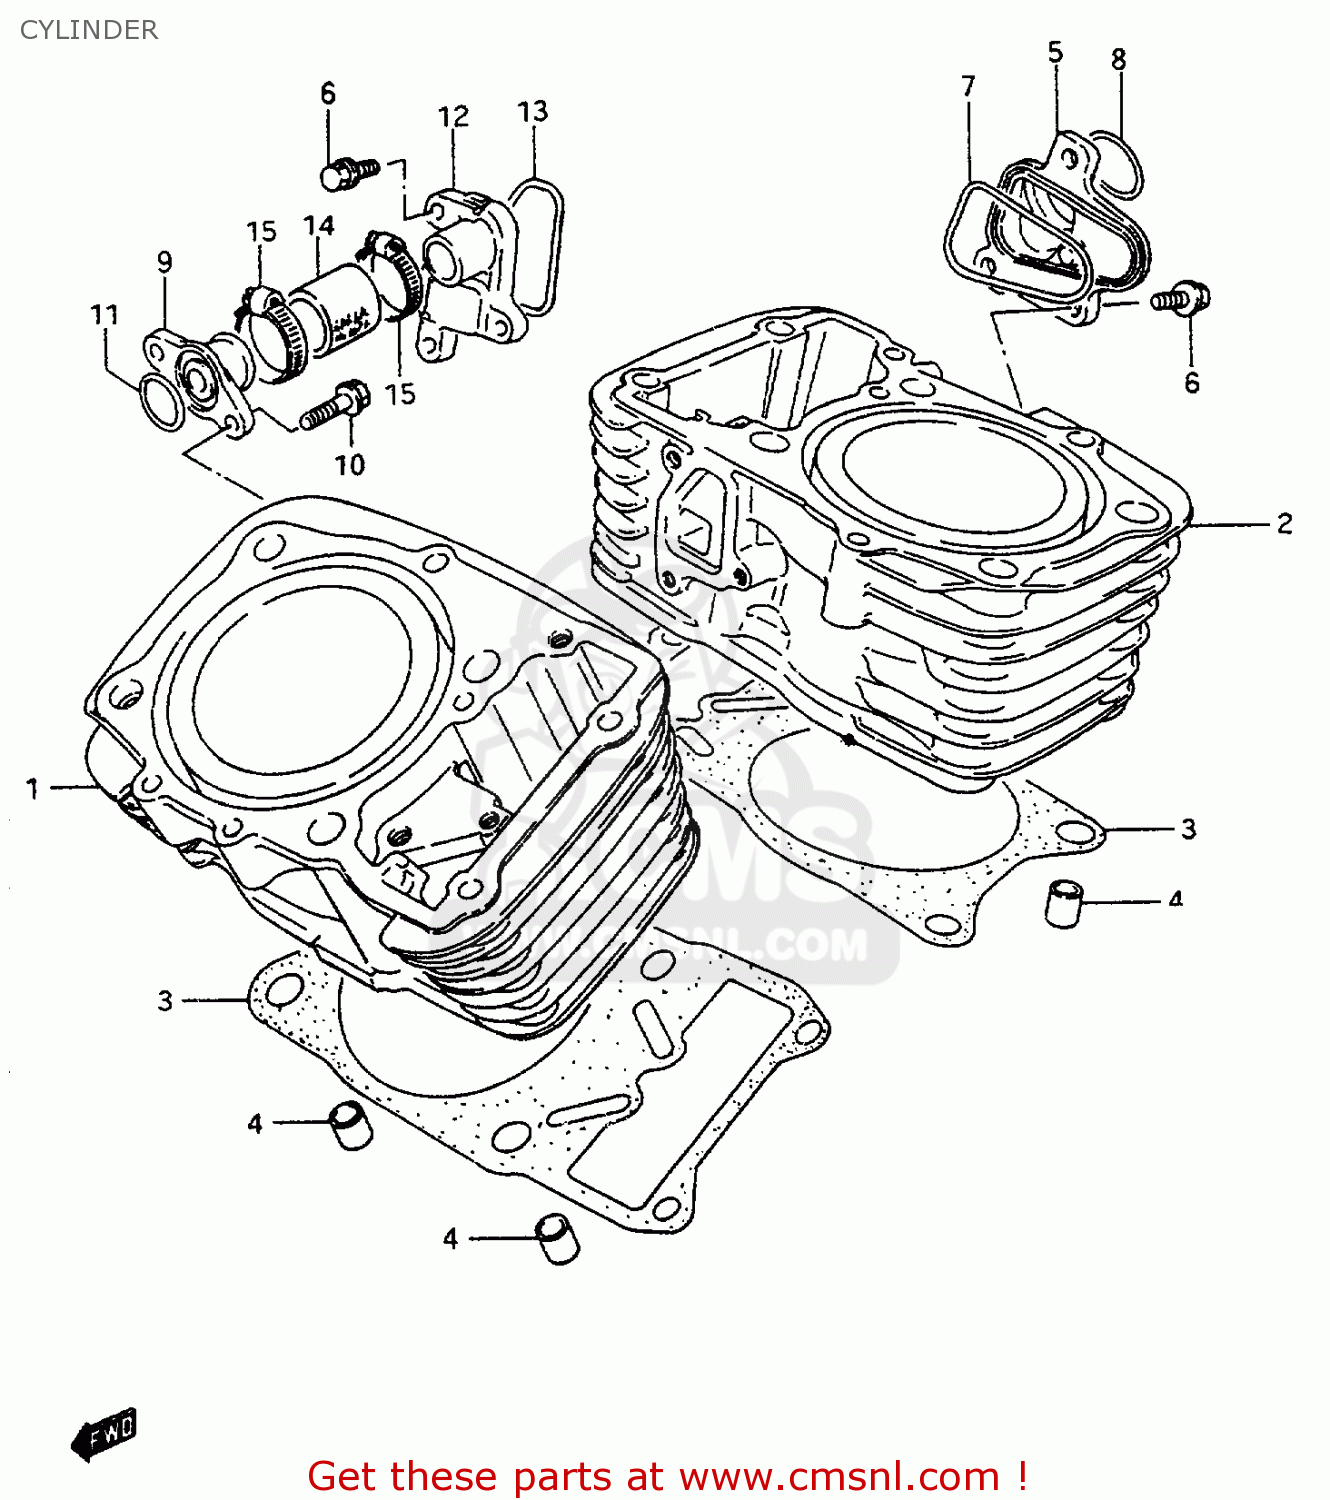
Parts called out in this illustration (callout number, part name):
1	CYLINDER,FR
2	CYLINDER, REAR
3	GASKET,CYLINDER
4	PIN
5	CHAMBER,WATER,INLET
6	BOLT
7	O RING,INLET WATER CHAMBER
8	O RING(D:2.3,ID:24.4)
9	UNION,WATER INLET
10	BOLT
11	O RING(D:2.4,ID:15.8)
12	CHAMBER,WATER OUTLET
13	O RING,OUTLET WATER CHAMBER
14	HOSE,RADIATOR JOINT NO.1
15	CLAMP
